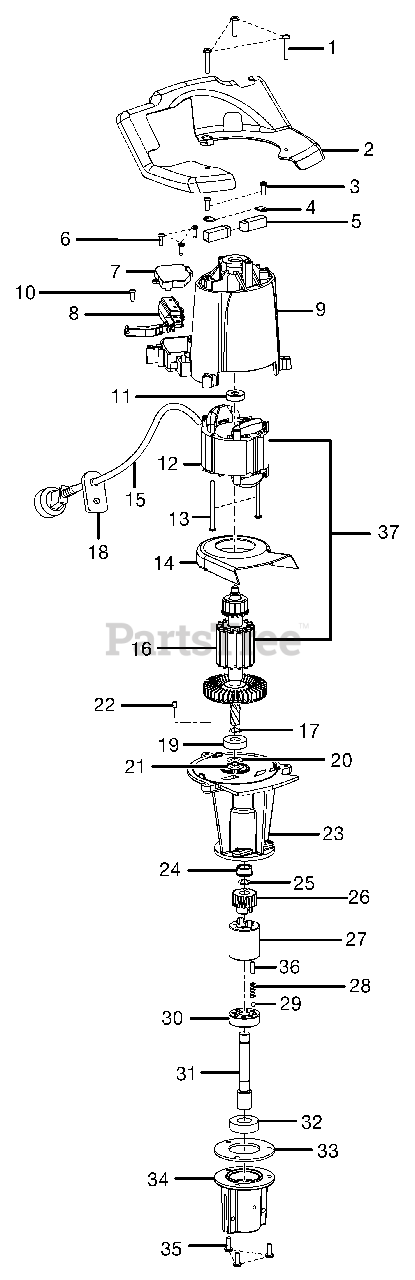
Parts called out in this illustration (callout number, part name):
1	SCREW (M5 X 26 mm)
2	INNER HOUSING
3	SCREW (8-16 x 5/8 in. PAN HD.)
4	BRUSH TUBE CLAMP
5	BRUSH TUBE ASSEMBLY
6	SCREW (M3.5 X 16 mm)
7	SWITCH COVER
8	SWITCH, ON-OFF ASSEMBLY
9	MOTOR HOUSING
10	SCREW (M4 x 18 mm PAN HD.)
11	BALL BEARING (NTN 608ZZ C3/1E)
12	FIELD ASSEMBLY
13	SCREW (8-10 X 2-1/2 in. PAN HD.)
14	FAN SHROUD
15	POWER CORD
16	ARMATURE ASSEMBLY
17	RETAINING RING
19	BALL BEARING
20	FELT SEAL
21	FIBRE WASHER RING
22	RUBBER PLUG
24	FLANGE BEARING
29	BALL (5.96 mm)
30	CLUTCH PLATE
31	OUTPUT SHAFT
32	BALL BEARING (6003)
34	GEAR CASE
35	SCREW (M5 x 14 mm)
36	PLUG (6 mm x 17 mm)
37	MOTOR ASSEMBLY
